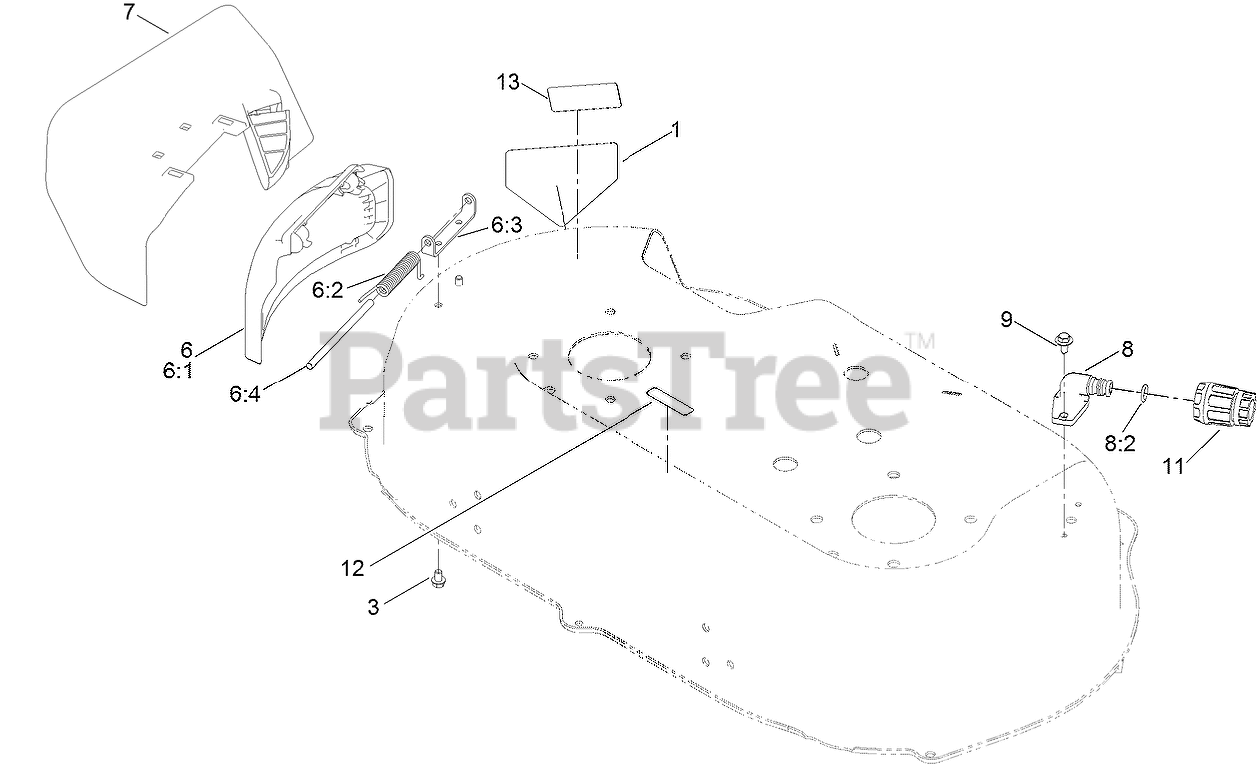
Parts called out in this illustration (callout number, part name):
1	DECAL-DANGER
6	SIDE DEFLECTOR SERVICE ASM
6:1	DEFLECTOR-SIDE
6:2	SPRING-TORSION, COVER
6:3	BRACKET-COVER
7	CHUTE-DISCHARGE, SIDE
8	FITTING-WASHOUT
8:2	O-RING
9	SCREW-HWH, THD ROLL
11	CONNECTOR-HOSE
12	DECAL-WARNING
13	DECAL-PLACEMENT, FOOT
